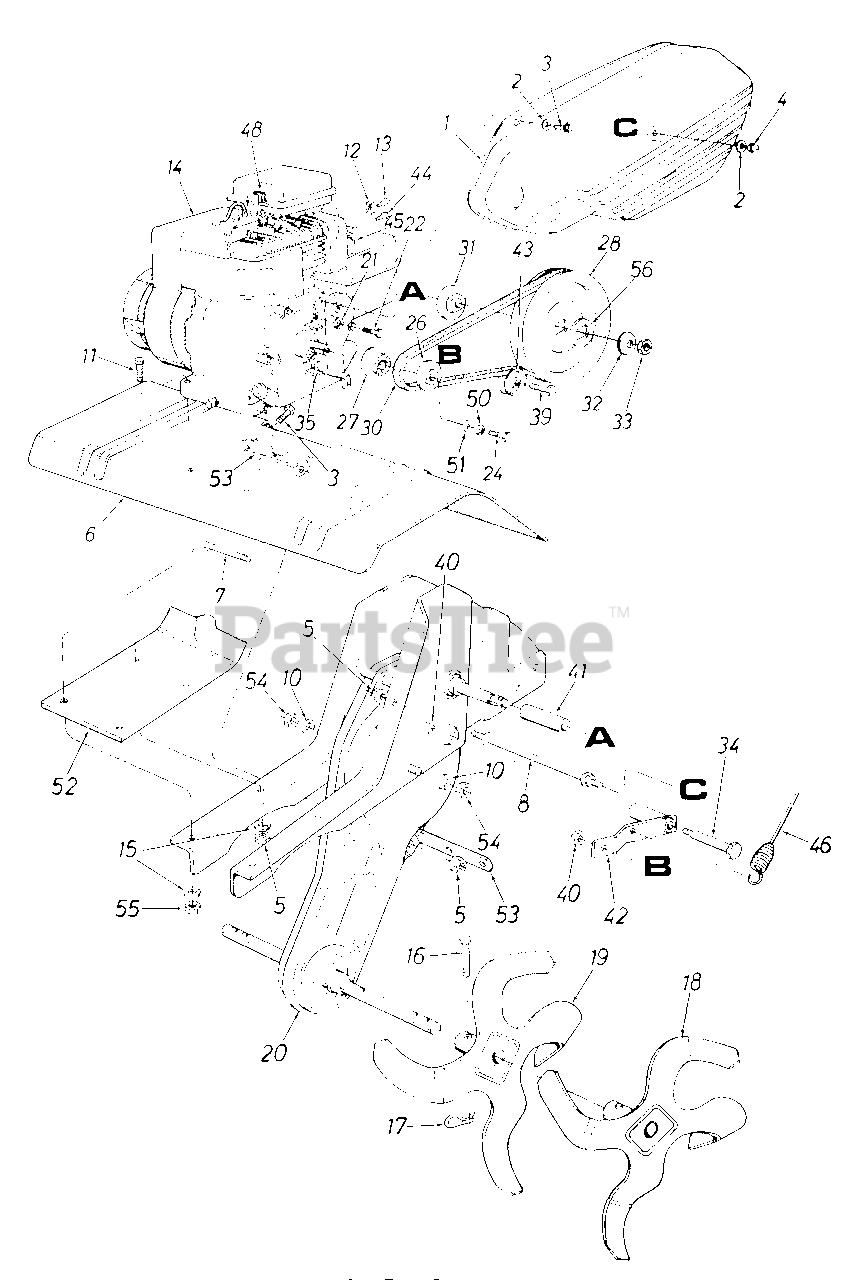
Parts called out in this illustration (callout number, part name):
2	Fl-Wash. .266" I.D. x .625" O.D.
3	Hex Wash. Hd. TT-Tap Scr. 1/4-20 x .5" Lg.
4	Hex L-Stop Nut 1/4-28 Thd.
5	Hex Flange Top L-Nut 5/16-18 Thd. (Gr. 5)
8	Belt Cover Bolt
10	L-Wash. 7/16" I.D.
11	Hex Bolt 5/16-18 x 1.75" Lg.
12	Casing Clamp
13	Hex Sems Scr. #10-32 x .62" Lg.
14	Engine
15	Spec. L-Nut 5/16" I.D.
16	Clevis Pin .375" Dia. x 1.75" Lg.
17	Internal Cotter Pin
20	Chain Case Ass'y. Comp.
21	L-Wash. 5/16" I.D.
22	Hex Bolt 5/16-24 x .5" Lg.
24	Hex Bolt 3/8-24 x 1.25" Lg
26	Outer Engine Pulley Half
27	Inner Engine Pulley Half
28	Fl-Pulley 6" Dia.
30	"V"-Belt
31	Pulley Mounting Adapter
32	Bell-Wash. .535" I.D. x 1.5" 0.D.
33	Hex Jam Nut 1/2-20 Thd. (Gr. 5)
34	Shld. Bolt .498" Dia. x 1.45" Lg.
39	Hex Cap Bolt 3/8-16 x 1.25" Lg.
40	Hex Cent. Jam Nut 3/8-16 Thd
41	Spacer .64" I.D. x 2.4" Lg.
42	Tine Idler Brkt. Ass'y.
43	Fl-Idler 2" O.D.
44	Hex Self-Tap Scr. #8-32 x .38"
45	Muffler Deflector
46	Clutch Control Cable
48	Spark Plug Boot
50	L-Wash. 3/8" I.D.
51	Fl-Wash. 3/8" I.D. x 1" O.D.
54	Hex Nut 7/16-20 Thd.
55	Hex Nut 5/16-18 Thd.
56	Bearing Retainer Washer
